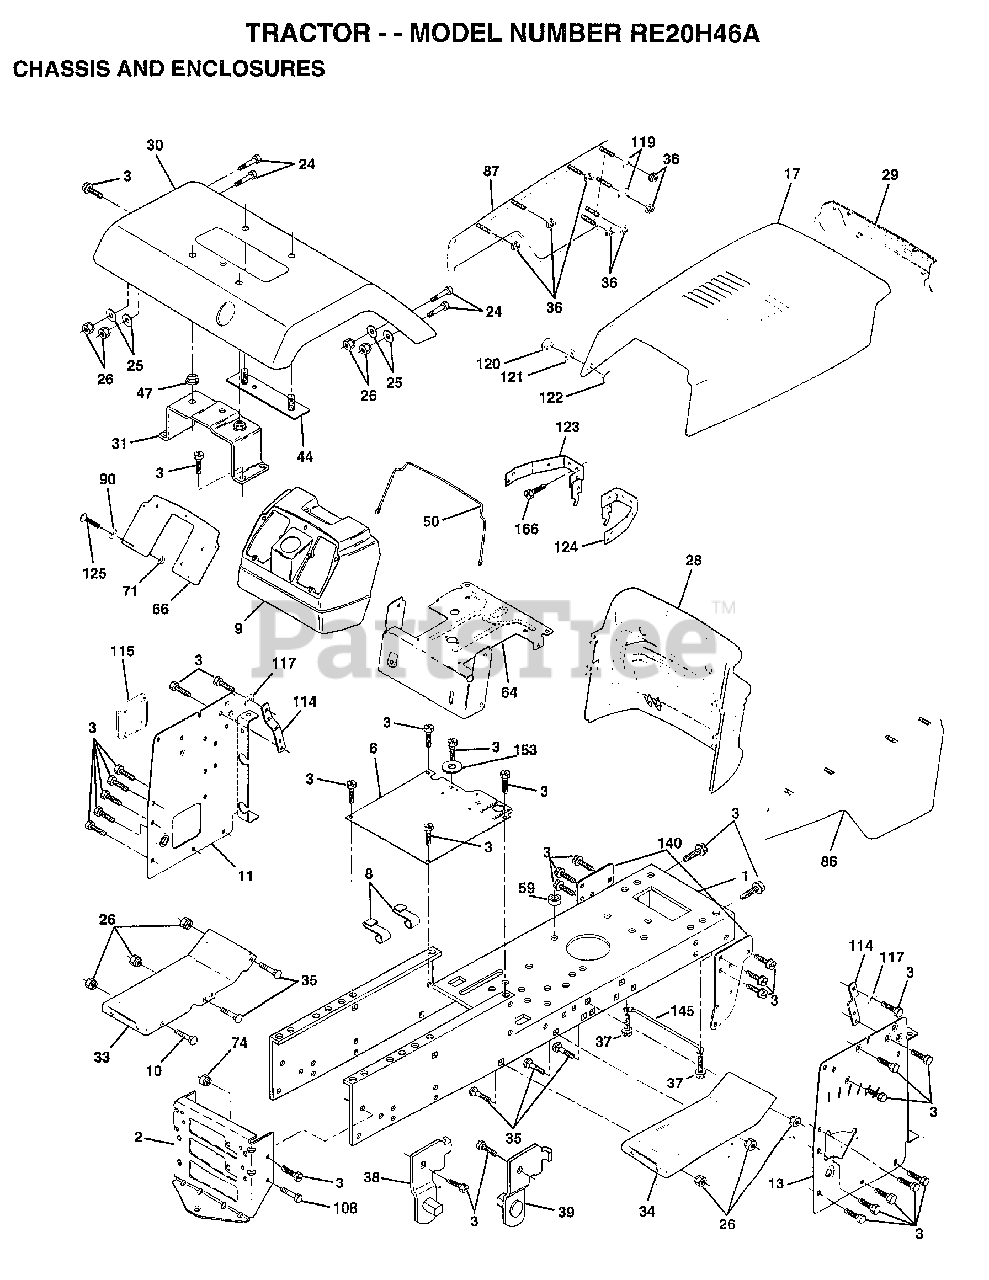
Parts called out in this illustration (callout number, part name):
1	CHASSIS.STAMPING
3	SCREW
6	SADDLE
8	"CLIP,INSULATOR"
9	DASH.PLASTIC.BLK
11	DASHBRD.PANEL.LH
13	DASHBRD.PANEL.RH
17	HOOD/GRILLE ASS'Y
24	BOLT
25	WASHER
26	NUT
29	LENS.YT.GT.SEARS
30	FENDER.PNT.
31	BRKT.ASM.FENDER
33	FOOTREST.LH.LT/GT
34	FOOTREST.RH.LT/GT
35	BOLT
36	PAL NUT LT
37	SCREW LT
38	BRACKET ASM LH
39	BRACKET ASM RH
44	STRAP ASM FENDER
47	NUT-PUSH YT
50	ROD.SUPT.HOOD 1PC
64	DASH.LOWER.LT
66	PLATE.SIKLSCREEN.DASH
71	NUT HXKEP 1/4X20
90	WASHER PM
114	BRACKET.SUPT.DASH
115	COVER ACCESS
117	WASHER.SERRATED.
119	WASHER
120	RIVET.RATCH.FEMAL
121	WASHER.NYLON
122	RIVET.RATCHET.MAL
123	BRKT ASM PIVOT LH
124	BRKT ASM PIVOT RH
125	SCREW
140	BRKT SUSPENSION
145	"ROD POVOT,CHASSIS"
153	WASHER GT
166	"SCREW,HWHD.HI-LO#13-16X3/4"
